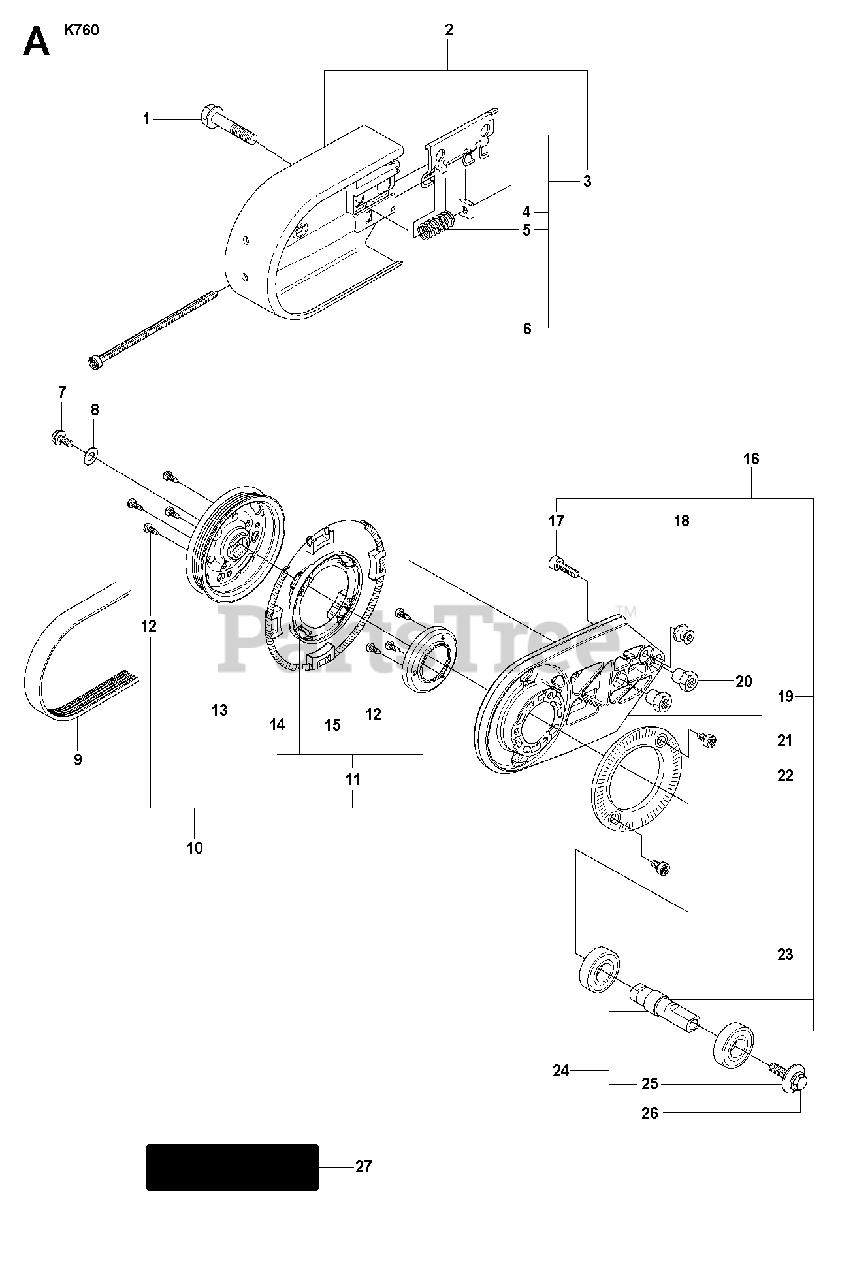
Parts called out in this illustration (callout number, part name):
2	BELT GUARDIncl. 3
3	BELT TENSIONER ASSYIncl. 4 - 6
5	COMPRESSION SPRING
6	SCREW CITXSCM
10	PULLEY ASSYIncl. 11 - 13
11	CASSETTEIncl. 12, 14 - 15
12	SCREW CCRPANT
13	PULLEY
16	BEARING HOUSINGIncl. 17 - 19, 21 - 23
17	SCREW ITXSCM
18	TORSION STOP
19	BEARING HOUSINGIncl. 20
21	SCREW ITXSCM
23	BALL BEARING
24	SHAFTIncl. 25 - 26
27	LABELJapan only
